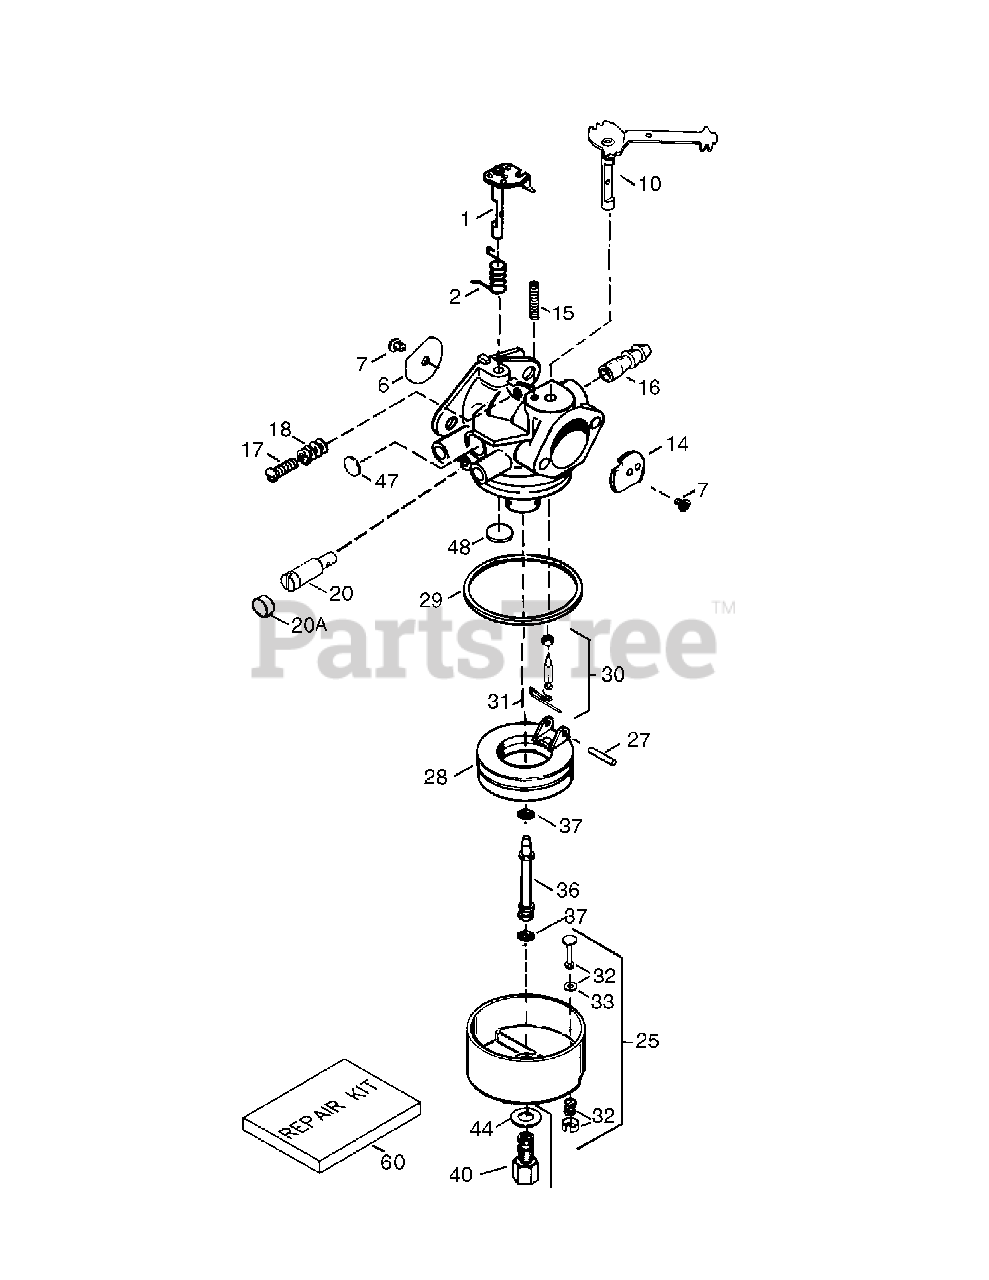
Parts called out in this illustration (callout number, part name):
1	Throttle Shaft & Lever Assy.
2	Throttle Return Spring
6	Throttle Shutter
7	*Shutter Screw
10	Choke Shaft & Lever Assy.
14	Choke Shutter
15	Choke Positioning Spring
16	Fuel Fitting
17	Idle Speed Screw
18	Tension Spring
20	Idle Resrictor Scew
20A	Idle Resrictor Scew Cap
25	Float Bowl Assy.
27	*Float Shaft
28	Float
29	*Float Bowl O-Ring
30	*Inlet Needle, Seat & Clip
31	Spring Clip
32	Bowl Drain Assy.
33	*Plunger Drain Gasket
36	Main Nozzle Tube
37	*Main Nozzle Tube O-Ring
40	High Speed Bowl Nut
44	Bowl Nut Washer
47	*Welch Plug
48	*Welch Plug
60	Repair Kit (Includes Items *)
